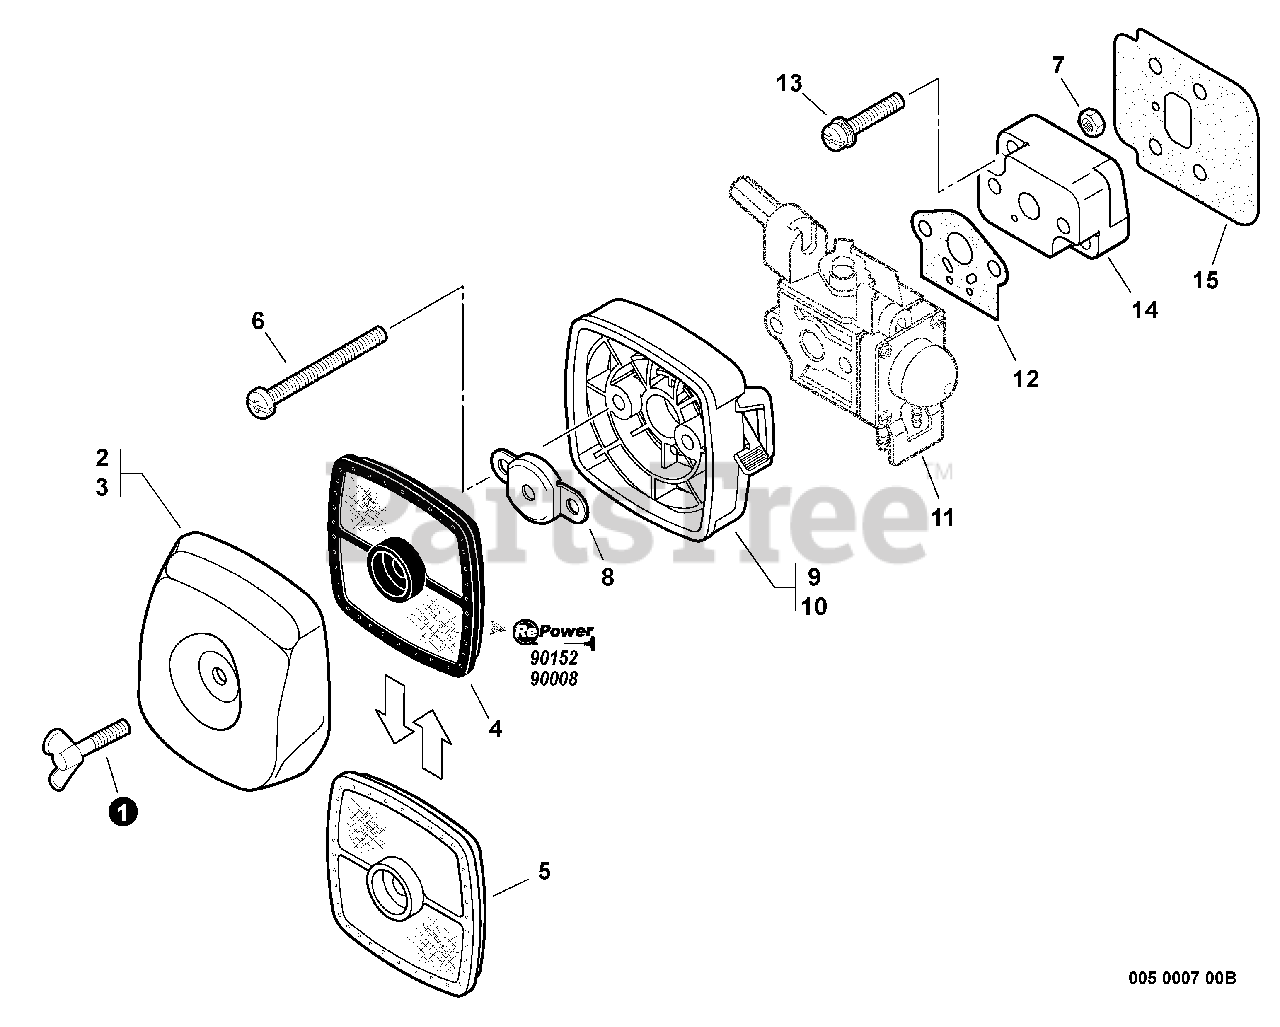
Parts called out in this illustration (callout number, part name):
1	THUMBSCREW
2	COVER, AIR FILTER - GRAY
3	COVER, AIR FILTER - BLACK
4	FILTER, AIR - DOUBLE LAYER
5	FILTER, AIR - SINGLE LAYER
6	SCREW - 5X65
8	PLATE, PREVENT
9	CASE, AIR FILTER - GRAY
10	CASE, AIR FILTER - BLACK
11	CARBURETOR
12	GASKET, INTAKE
13	SCREW - 5X22
14	INSULATOR, INTAKE
15	SHIELD, INTAKE
16	RePower FILTER KIT
17	Repower TUNE-UP KIT
